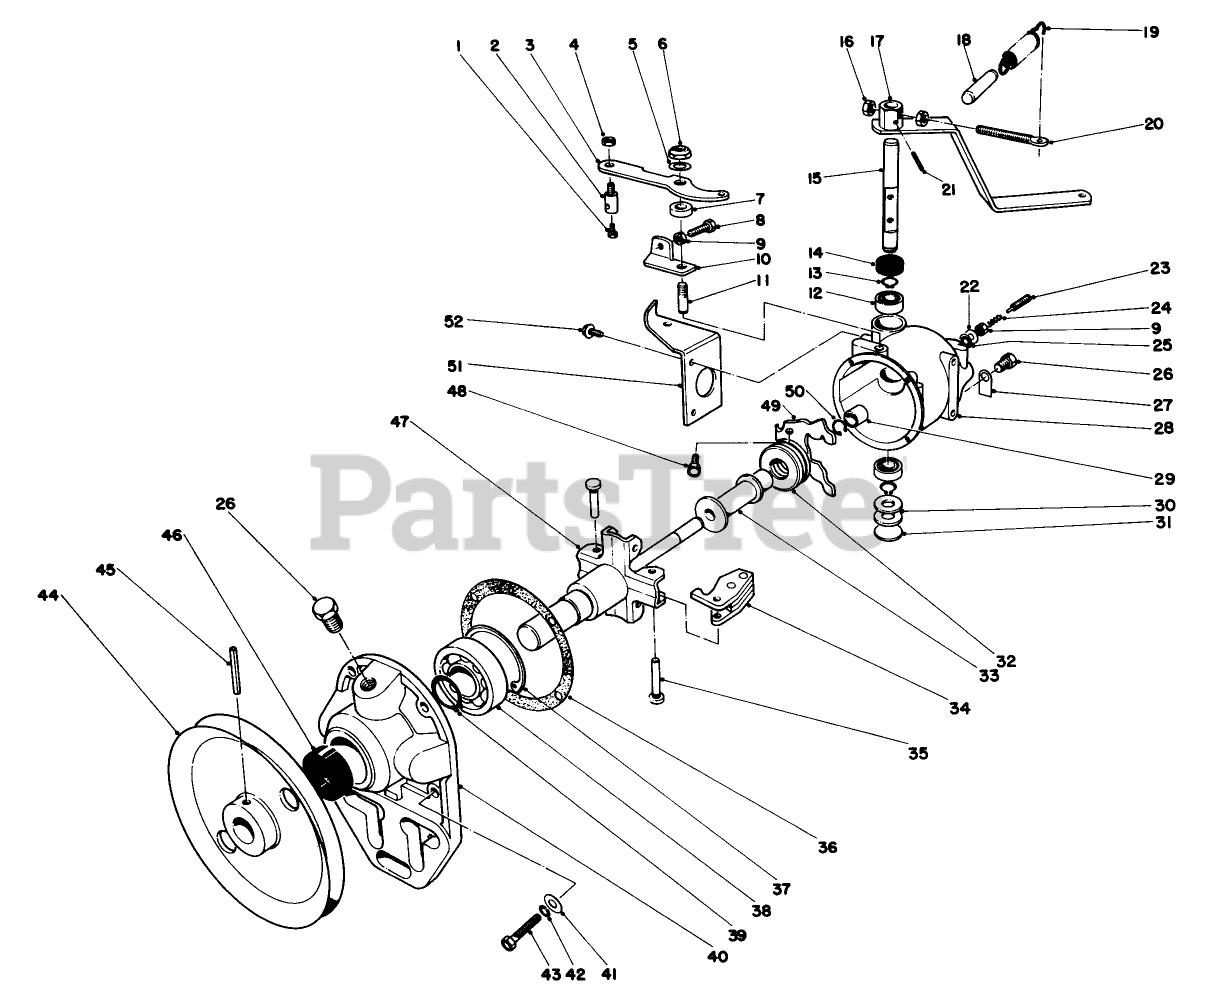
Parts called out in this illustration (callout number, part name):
1	SCREW-HH
2	SWIVEL
3	Speed Change Lever
4	NUT-LOCK, NI
5	WASHER
6	STOP NUT
7	Spacer
8	SCREW-HH
9	NUT-HEX
10	Stop Bracket
12	BALL BRG
13	EXT SNAP RING
14	OIL SEAL
15	Rocker Shaft
16	NUT-HEX
17	THROTTLE LEVER ASM
18	FORCED IDLE PLUG
19	SPRING
20	EYESCREW
21	PIN-ROLL
22	Shim Washer
23	BUMPER SCREW
24	BUMPER SPRING
25	SEALING WASHER
26	PIPE PLUG
27	OIL LEVEL TAG
29	DRIVE SHAFT BUSHING
30	WASHER
31	WELCH PLUG
32	Thrust Bearing
33	Thrust Sleeve
34	WEIGHT ASM
35	WEIGHT PIN
36	GASKET
37	INT BEVELED
38	BEARING-BALL
39	RETAINING RING
40	FLANGE
41	WASHER-FLAT
42	WASHER-LOCK
43	10-24 X 7/8 IND HD SC
44	Pulley
45	PIN-SPRING
46	OIL SEAL
47	SPIDER & SHAFT ASM
48	MACHINE SCREW
50	RETAINING RING
51	Bracket
52	SCREW
